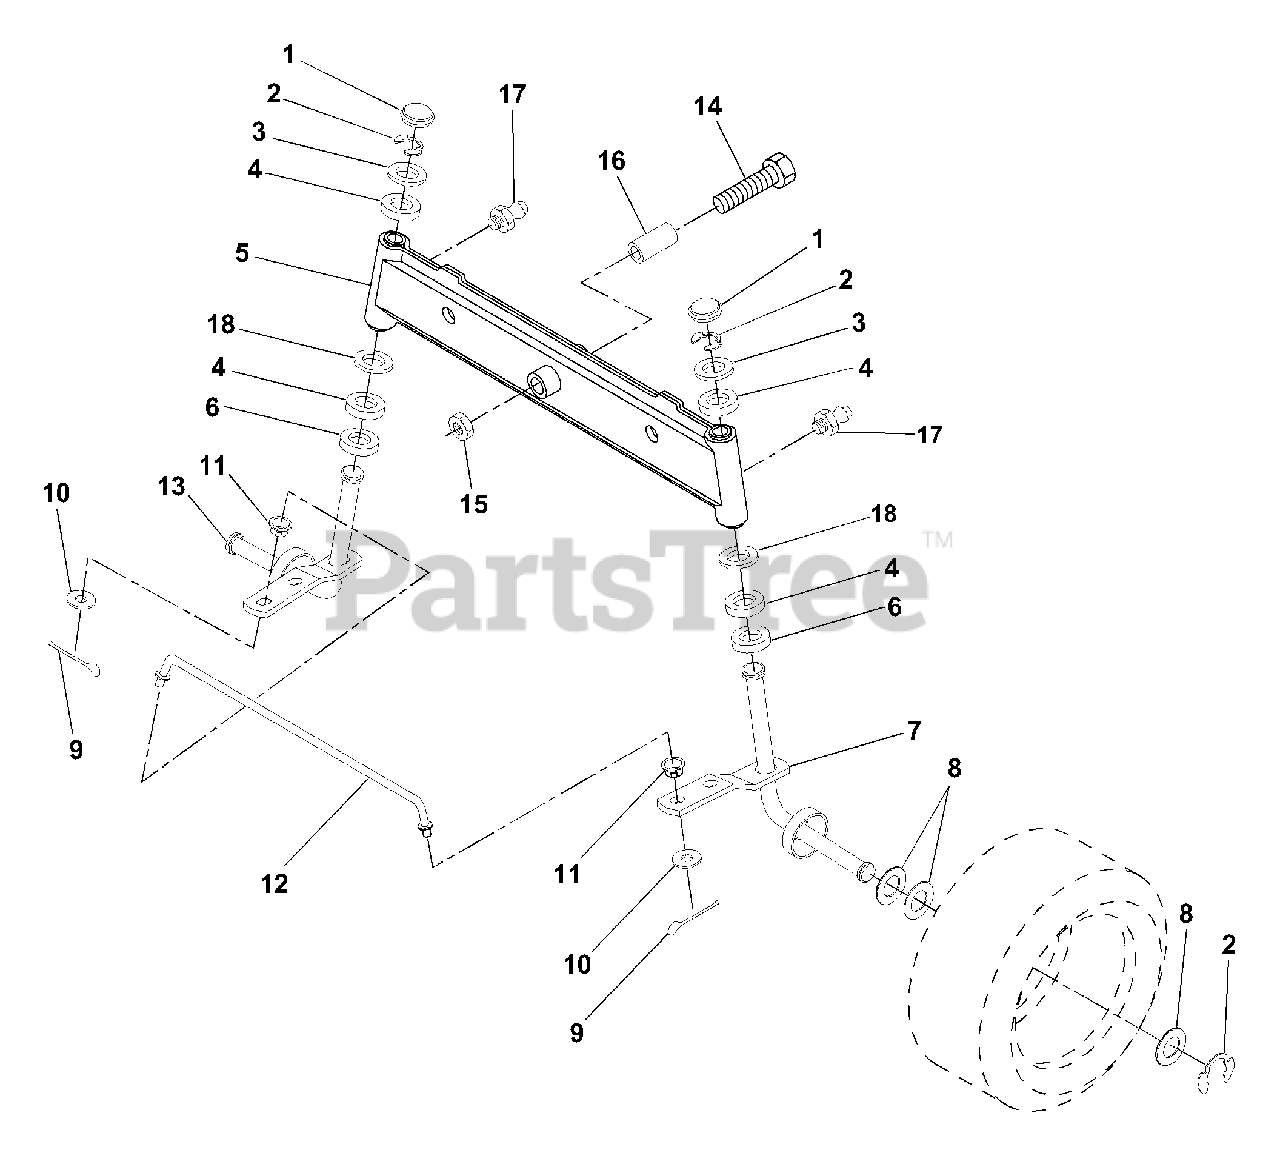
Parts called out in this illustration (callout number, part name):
1	Cap, Spindle
2	Ring, Clip
3	Washer 25/32 x 1-5/8 x 16 Ga.
4	Nyliner
5	Axle, Front
6	Bearing, Thrust
7	Spindle, R.H. Asm.
8	Washer 25/32 x 1-1/4 x 16 Ga.
9	Pin, Cotter 1/8 x 3/4
10	Washer 13/32 x 13/16 x 16 Ga.
12	Rod, Tie
13	Spindle, L.H. Asm.
14	Bolt Hex 5/1-11 x 3-1/2
15	Nut, Lock Flange 5/8-11
16	Spacer, Bearing Axle
17	Fitting, Grease
18	Washer 27/32 x 1-1/4 x 16 Ga.
